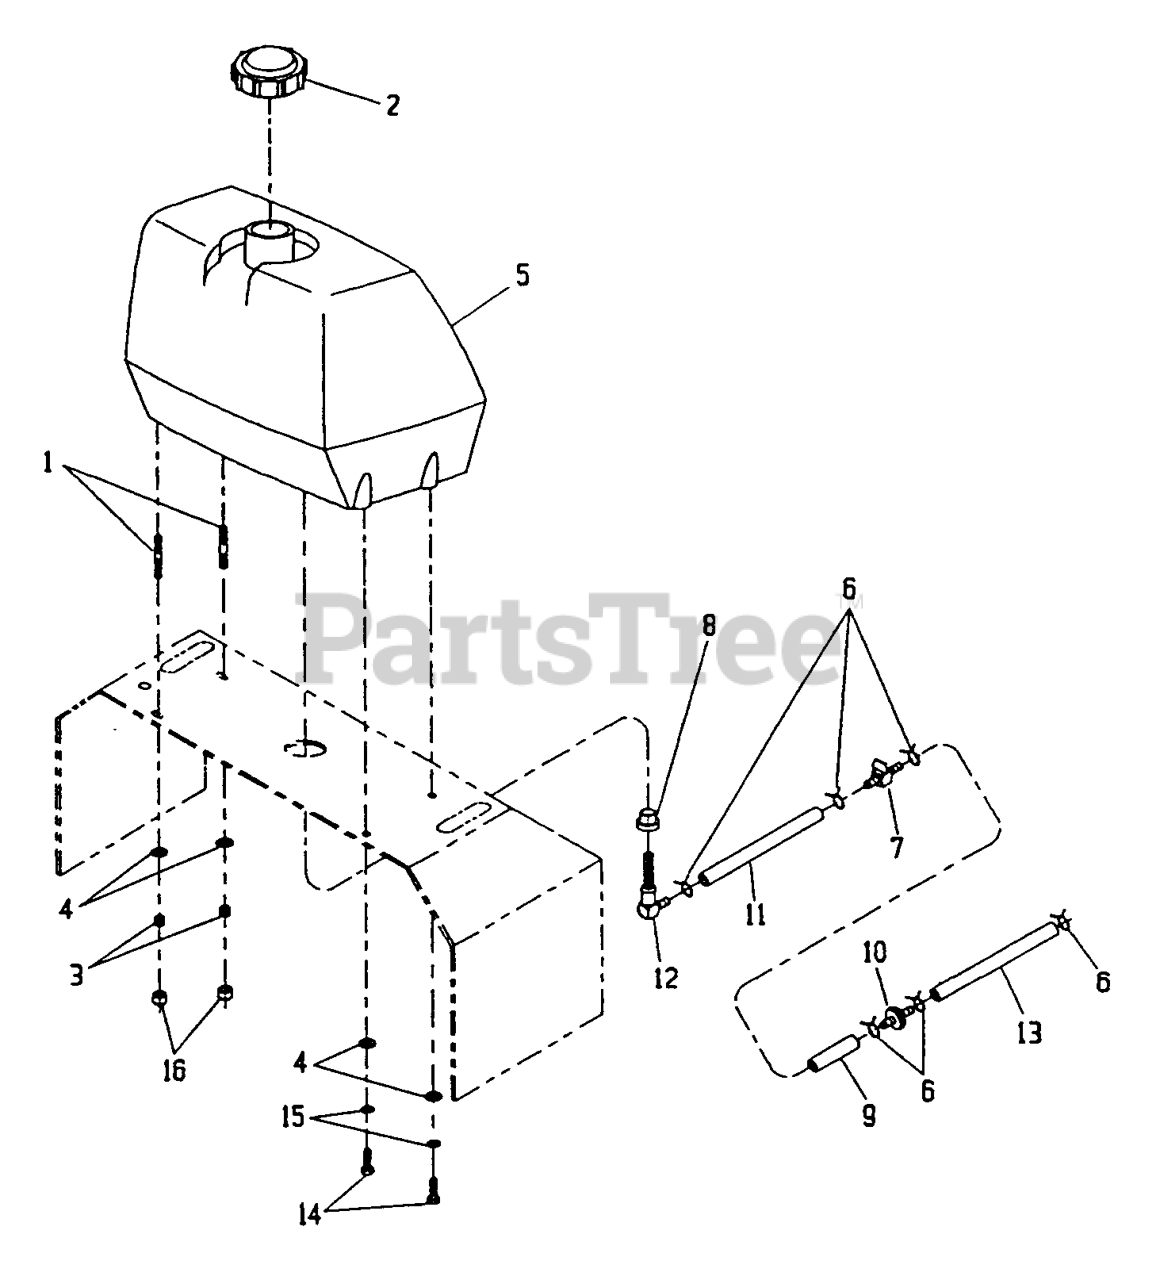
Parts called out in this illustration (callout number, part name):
1	STUD
2	CAP-FUEL
3	SPRING-TANK, FUEL
7	VALVE-FUEL
9	HOSE-LINE, FUEL
12	ELBOW-TANK, FUEL
15	WASHER-LOCK
